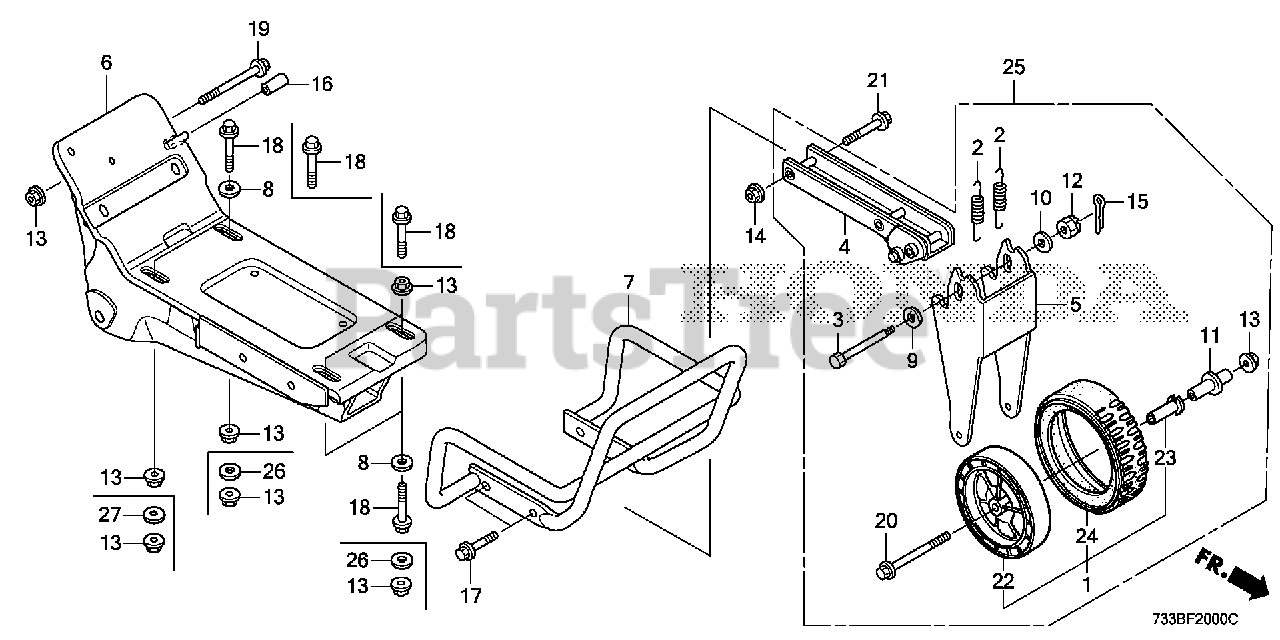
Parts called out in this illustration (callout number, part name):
1	WHEEL (8") *NH31* (MCKINLEY WHITE)
1	WHEEL
2	SPRING, RETURN
3	SHAFT, FR. WHEEL
4	BEAM, FR. WHEEL
5	ARM, FR. WHEEL
6	BED, ENGINE
7	GUARD, FR.
9	WASHER, CHUTE GUIDE
10	WASHER (8X22)
11	COLLAR, FR. WHEEL
12	NUT, CASTLE (8MM)
13	NUT, FLANGE (8MM)
14	NUT, FLANGE (10MM)
15	PIN, COTTER (2.0X22)
15	PIN, COTTER (2.0X35)
16	BULK HOSE, VINYL (10X14X3000) (10X14X20)
17	BOLT, FLANGE (8X20) Use up to Engine SN 1609606.
18	BOLT, FLANGE (8X35)
19	BOLT, FLANGE (8X70)
20	BOLT, FLANGE (8X80)
21	BOLT, FLANGE (10X40)
22	HUB, WHEEL
23	BUSH, WHEEL
24	TIRE (8 INCH)
24	TIRE (8X2.0)
25	WHEEL ASSY., FR.
26	WASHER (8X22)
27	WASHER, ENGINE BED
